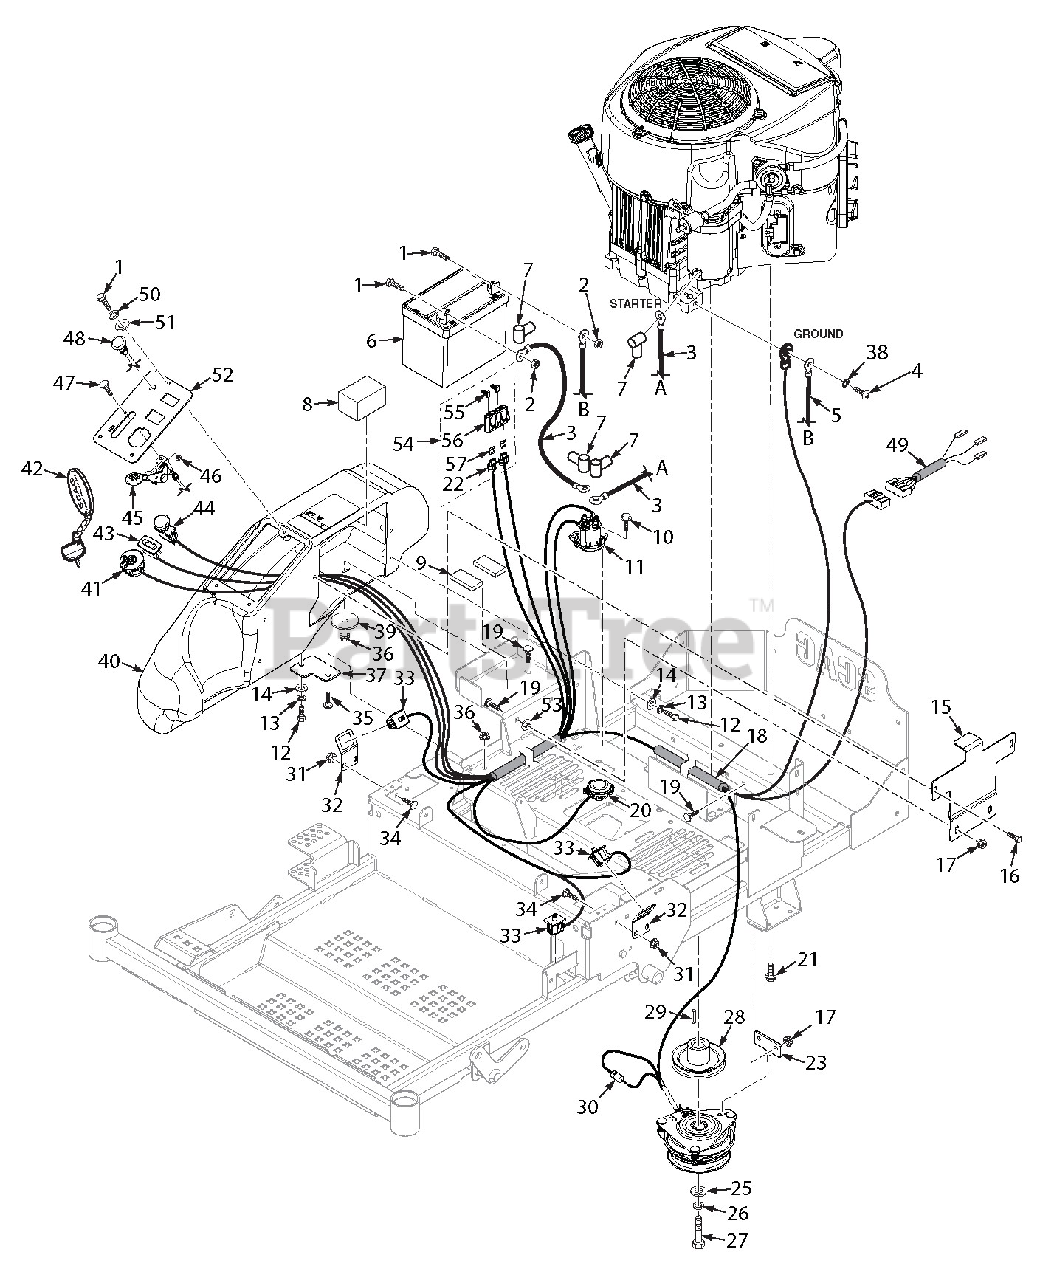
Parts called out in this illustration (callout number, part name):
1	Bolt, Hex Head 1/4-20 x 1/2"
2	Nut, 1/4-20 UNC
3	Cable, Battery - 18" Red
4	Screw, M8-1.25 X 16 Shakeproof
5	Cable, Battery - 31-1/2" Black
6	Battery, 12v - 230CCA
7	Rubber Boot
8	Pad, Battery - Rubber
9	Pad, Battery - Rubber
10	Screw, 1/4-20 x 3/4" Shakeproof
11	Solenoid, Sealed
12	Bolt, Hex Head 5/16-18 x 3/4"
13	Lockwasher, 5/16"
14	Flatwasher, 5/16-.375 x .875 x .083
15	Battery Hold Down
16	Bolt, Hex Head 5/16-18 x 1/2" Serrated Flange
17	Nut, 5/16-18 Elastic Stop
18	Wire Harness
19	Bolt, Carriage 5/16-18 x 3/4"
20	Switch, Double Pole - Twist
21	Screw, Hex Head 3/8-16 x 1-1/4" Self Tap
22	Fuse Holder
23	Plate, Anti-Rotation
24	Clutch, GT1
25	Flatwasher, 7/16-.496 x 1.75 x .25
26	Lockwasher, 7/16"
27	Bolt, Hex Head 7/16-20 x 3" w/Patch
28	Pulley, 4-1/2" Dia. - 1" Bore
29	Key, 1/4 x 1/4 x 1-1/4"
30	Diode (part of wire harness)
31	Nut, 1/4-20 Flange Elastic Stop
32	Bracket, Switch
33	Switch, Double Pole - Plunger
34	Bolt, Carriage 1/4-20 x 3/4"
35	Bolt, Carriage 5/16-181 x 1"
36	Nut, 5/16-18 Serrated Flange
37	Mounting Bracket, Fuel Tank Front
38	Lockwasher, 5/16" Ext.
39	Flatwasher, 3/8-.406 x 2.25 x .188
40	Console Tank, SZL
41	Ignition Switch
42	Key Fob Assembly
42	Key w/Shroud Only
43	Hourmeter
44	Switch, PTO
45	Throttle Cable
46	Nut, #10-24 Elastic Stop
47	Bolt, Carriage #10-24 x 1/2"
48	Choke Control
49	Wire Harness Adapter, Kawasaki"
50	Lockwasher, 1/4"
51	Flatwasher, 1/4-.312 x .750 x .065
52	Instrument Panel w/Decal
53	Nut, 5/16 Push-On
54	Double Fuse Assembly
55	Clip, Wire
56	Cover, Double
57	Fuse, 20 Amp
